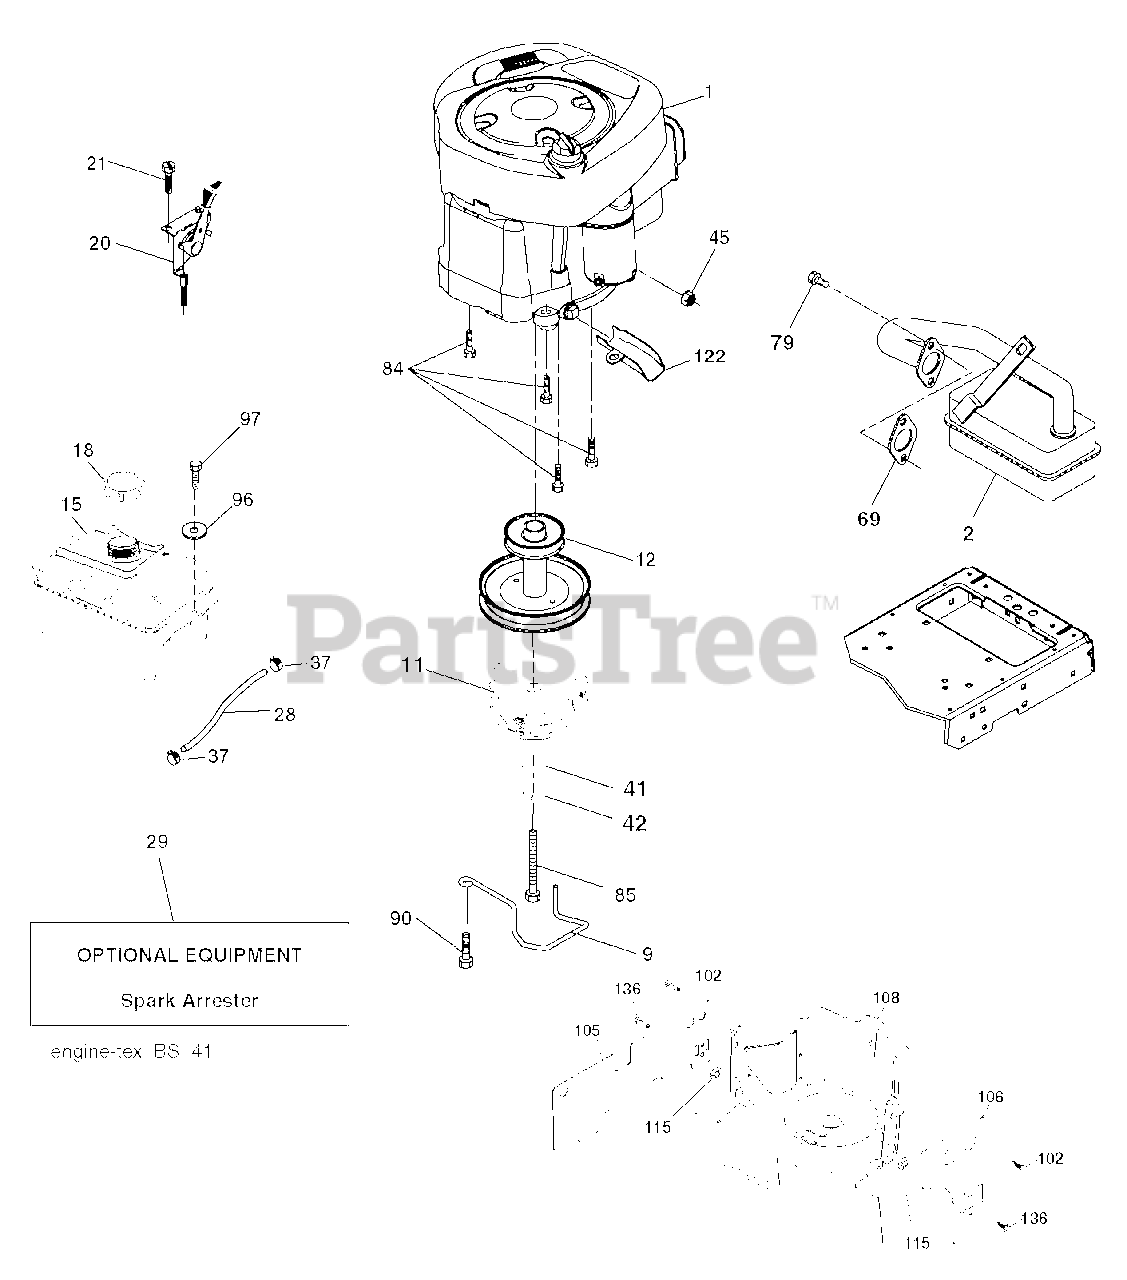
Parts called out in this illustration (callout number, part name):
9	KEEPER.BELT.ENGINE.3.25
11	CLUTCH
12	PULLEY.ASM.ENG.OGURA.3
15	TANK FUEL FRT 1.5 GAL
18	CAP ASM.FUEL.2.25"FR.
20	CONTROL.TH/CK.C.
21	SCREW.#10 X 0.750.BOS THREAD
28	LINE.FUEL.20
29	ARRESTER SPARK (OPTIONAL)
37	HOSE CLAMP
42	LOCKWASHER
45	NUT
69	REPL BY 532 27 22-93
79	SCREW.SOCKET HD.5/16-1
84	SCREW.3/8-16
85	BOLT HEX 7/16-20X4-1/4"
90	SCREW 3/8-16X1
97	SCREW HEXWSHR 1/4-20X3/4
102	SCREW
115	PALNUT 1/4
122	EXTENSION DRAIN OIL
136	SCREW.1/4-20X5/8
